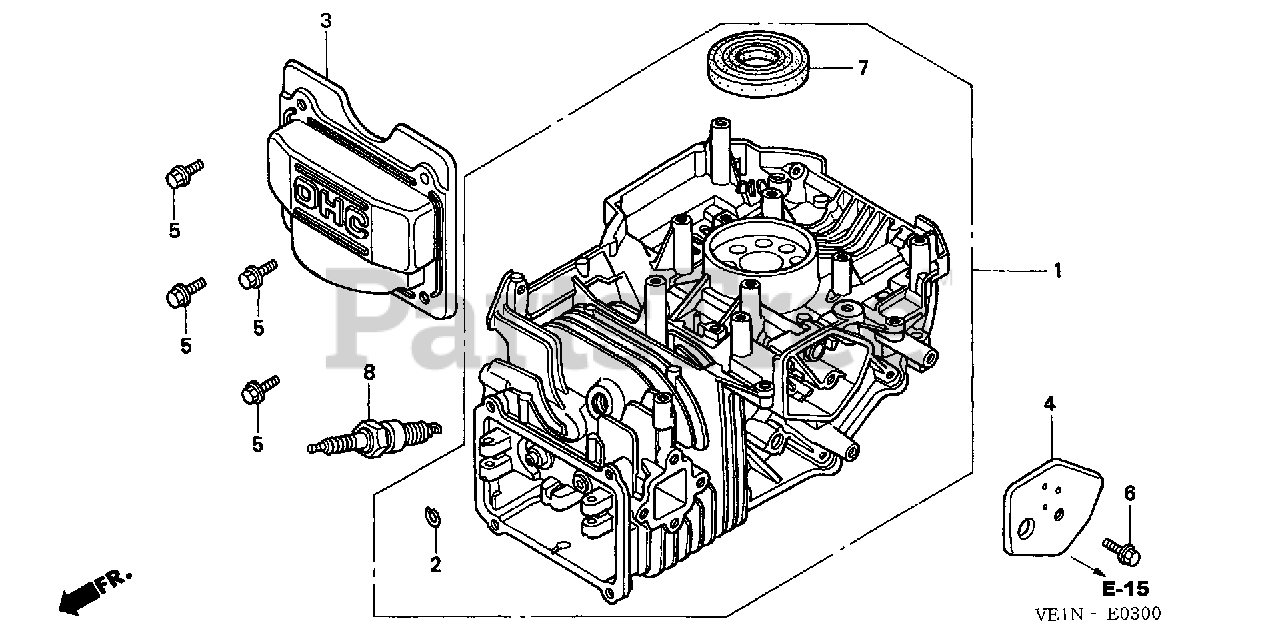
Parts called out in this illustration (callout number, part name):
1	CYLINDER ASSY.
2	CLIP, VALVE GUIDE
3	COVER, CYLINDER HEAD
3	COVER, HEAD
4	COVER, BREATHER (BREATHER VALVE ASSY.)
5	BOLT, FLANGE (6X12) (CT200)
6	BOLT, FLANGE (6X14) (CT200)
7	OIL SEAL (25.4X62X6)
8	SPARK PLUG (BPR6ES) (NGK)
